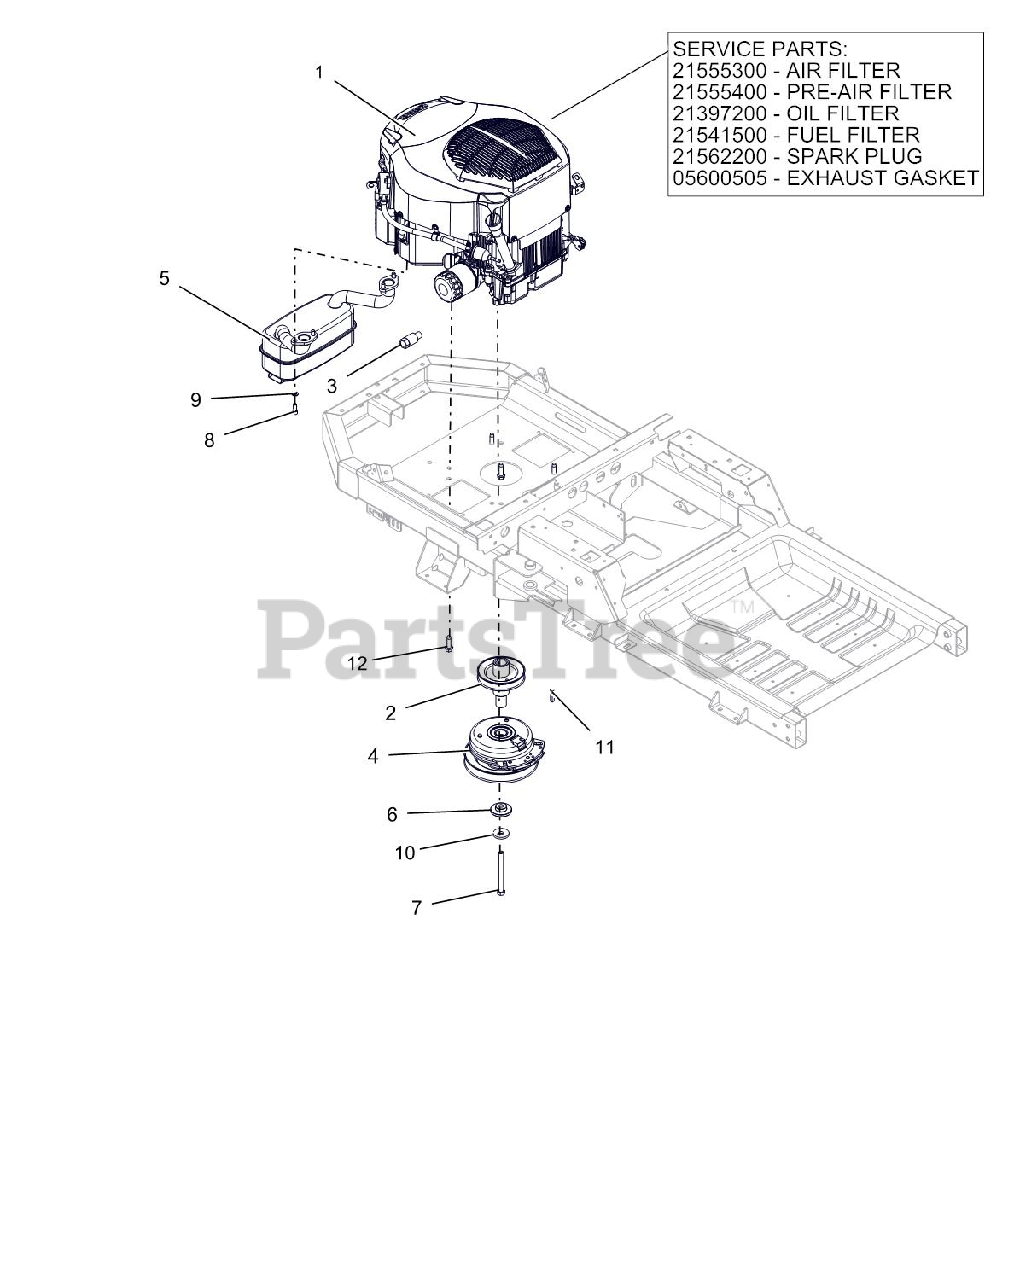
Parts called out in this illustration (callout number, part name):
1	FILTER, OIL - KOH CV20
1	FILTER, FUEL
1	GASKET, MUFFLER COURAGE TWIN
1	AIR FILTER, KOHLER
1	PRE CLEANER, KOHLER
1	PLUG, SPARK (RFI)
1	ENGINE,KOHLER TWIN 25 PRO W/SC
2	WLDMT, DRIVE SHEAVE-X YWZC
3	DRAIN, OIL
4	CLUTCH,105FTLB MONOPOLE 6.83"
5	MUFFLER - KOHLER
6	BSHG-FLG .469X1.06X.574X2.0
7	BLT-HEX.438-20X4.5GR8YZ NYTORQ
8	SCR-CAP .31-18X.75 S/HD
9	WSHR-LK .31X.078 REG YWZC
10	WASHER, 7/16" SPRING DISK
11	KEY-SQ .25 X 1.25 X .25 SAE
12	SCR-TAP .38-16X1.25 HWH TR YZ
